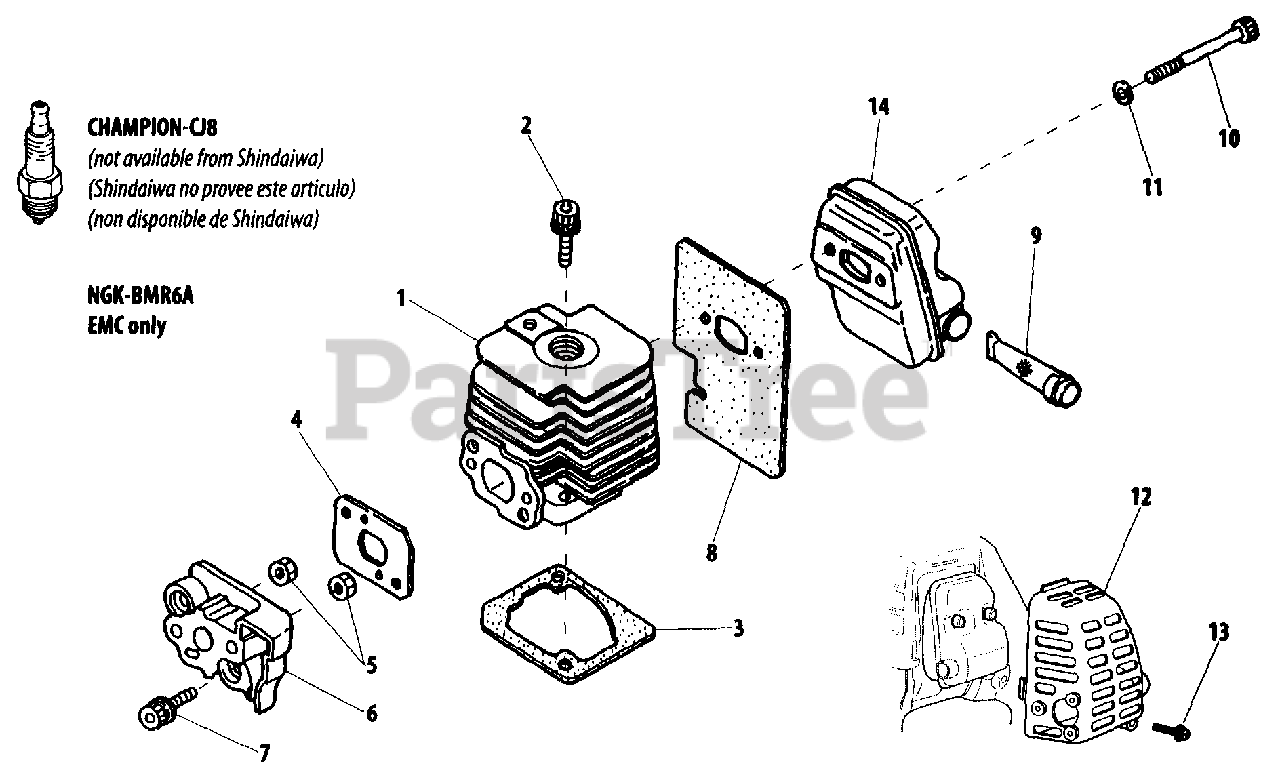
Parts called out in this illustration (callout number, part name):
1	CYLINDER
2	SCREW - 5X25
3	GASKET, CYLINDER
4	GASKET
5	NUT
6	INSULATOR
7	SCREW - 5X25
8	SHIELD, EXHAUST
9	SCREEN, SPARK ARRESTOR
10	SCREW - 5X40
11	WASHER - 5
12	COVER, MUFFLER
13	SCREW
14	MUFFLER
